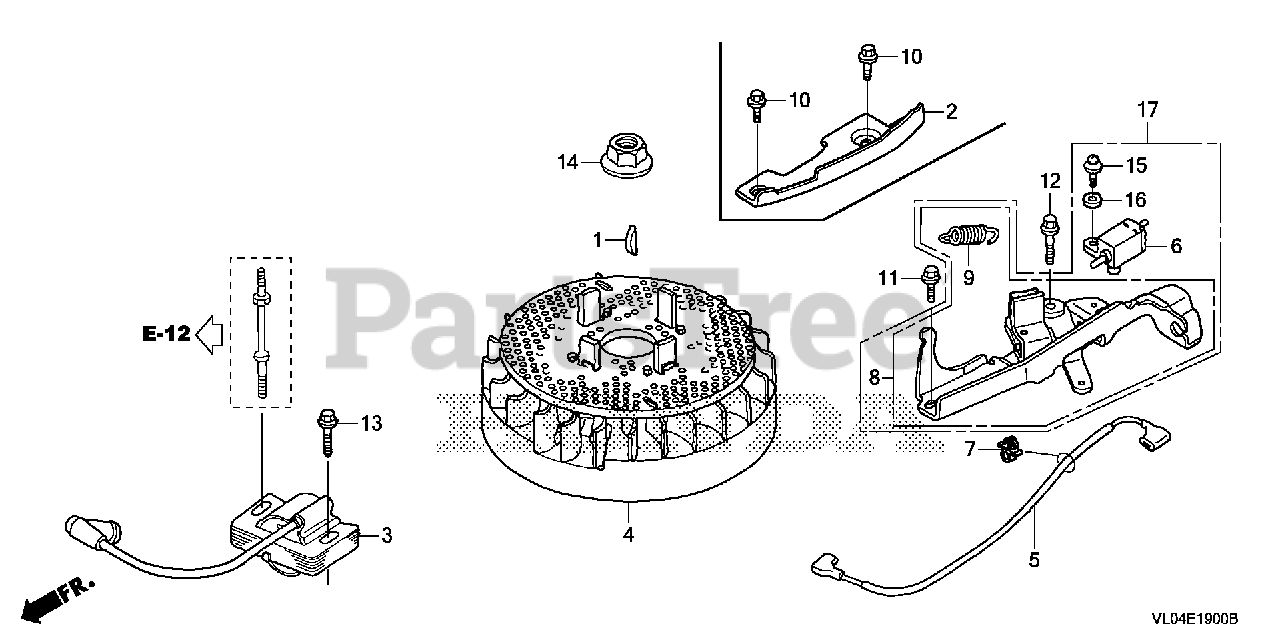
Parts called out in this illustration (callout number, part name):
1	KEY, SPECIAL WOODRUFF (25X18)
2	PLATE, SIDE
3	COIL ASSY., IGNITION (PHELON)
4	FLYWHEEL ASSY. (PHELON) (USE FOR IGN. COIL OF PHELON)
10	BOLT, FLANGE (6X12) (CT200)
13	BOLT, FLANGE (6X20) (CT200)
14	NUT, SPECIAL (14MM)
